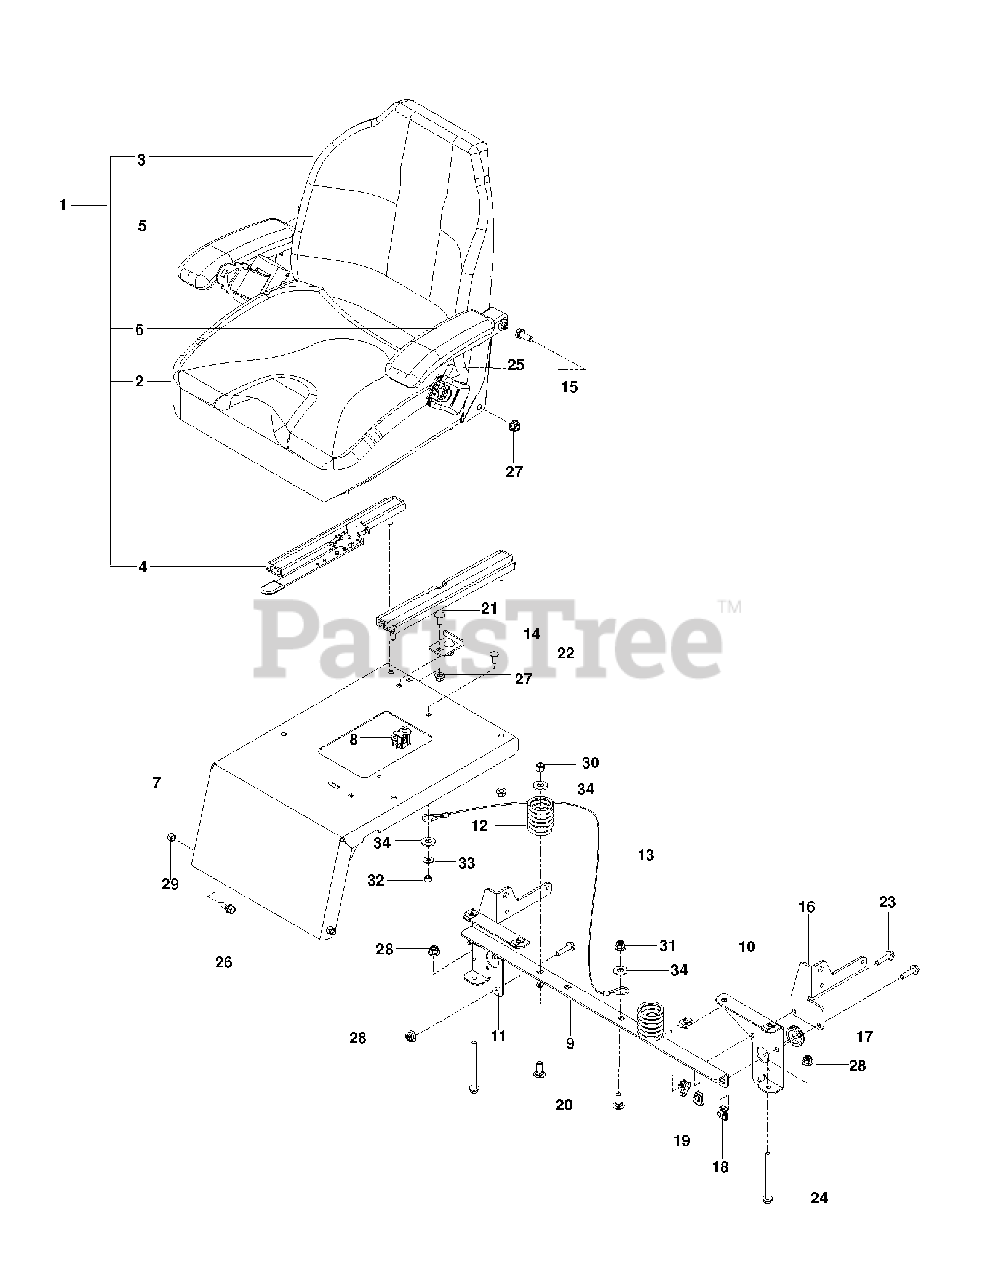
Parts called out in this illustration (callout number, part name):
2	ASSEM, CUSHION
3	ASSEM.BACK.SEAT
4	4"SINGLE LOCK TRACK SET W/HDWR
5	BLACK SELFSKIN-ARM PAD ONLY
6	LEFT SELFSKINNED 907 ARM W/BRK
8	SEAT SWITCH
9	SUPPORT, SEAT
10	SUPPORT, LT, BLK
11	SUPPORT, RT, BLK
12	SPRING, SEAT
13	SEAT LANYARD
14	STOP, SEAT - BLACK
16	MOUNT, SEAT BELT, BLACK
18	U-CLIP 5/16-18 NUT RETAINER
19	TIE WRAP, 8-3/8", W/CLIP
20	RHSNB 3/8C X 1
21	RHSNB 5/16-18 X 3/4
22	RHSNB 1/4C X 3/4
23	HHFS 5/16-18 X 1.25 TPBLT GD 5
24	HHFS 5/16-18 X 3 3/4
25	HCS 7/16-20 X .75 GD 5
26	SB 5/16-18 HEX HD GD5, BLK ZN
27	NUT HEX 7/16F LOCK RP
28	5/16-18 NYLOC FLANGE NUT
29	NUT 5/16 NYLOC
30	NUT 3/8-16 NYLOC
31	NUT 3/8-16 HEX FLG NYLOC ZD
32	NUT 1/4-20 NYLOC
33	WASHER 1/4 FLAT
34	WASHER 3/8 FLAT
